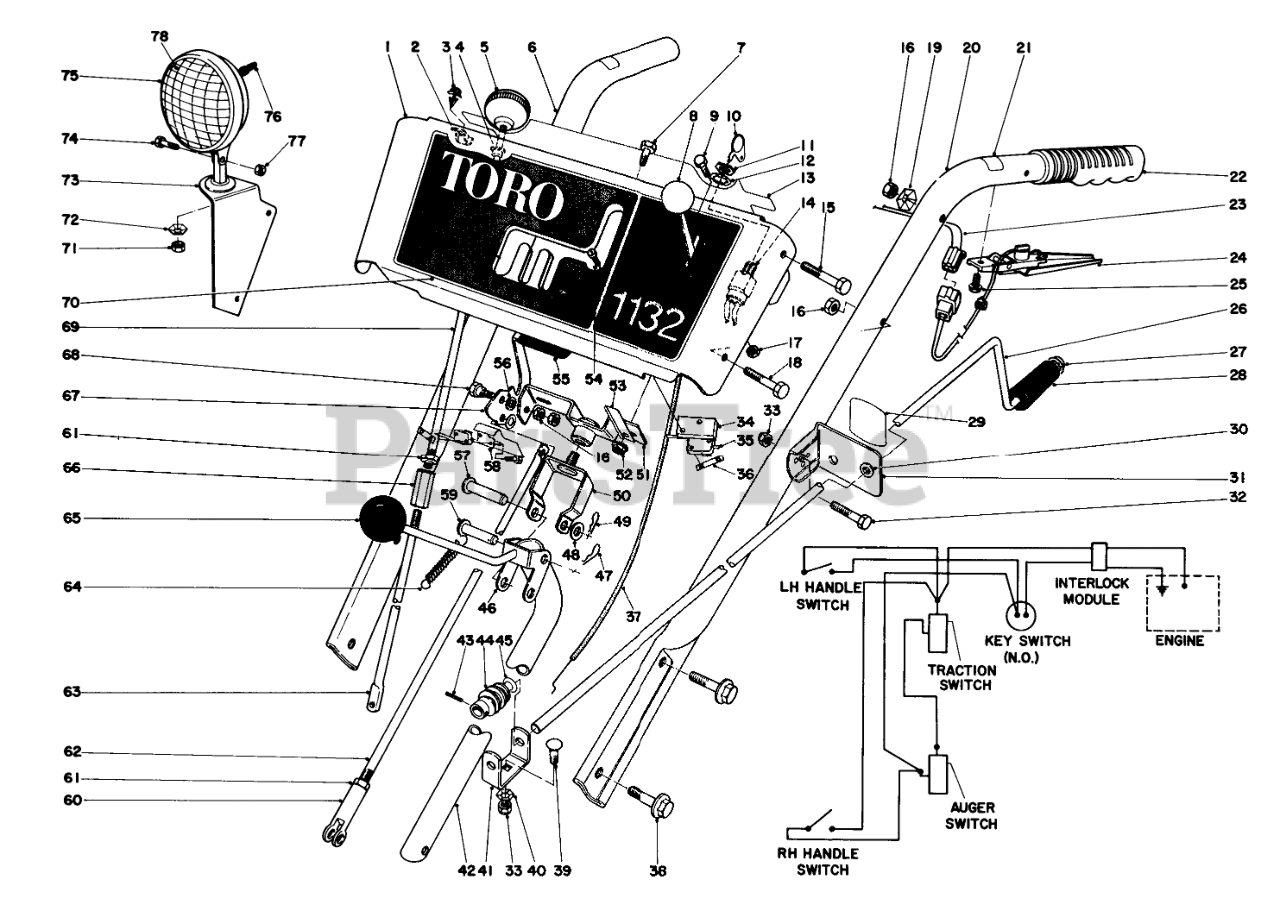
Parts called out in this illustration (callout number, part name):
1	Escutcheon Plate (Incl. Ref. #13&70)
2	WIRE CLAMP
3	Mounting Stud
4	NYLINER #6LI-FF TYPE 7
5	KNOB-LEVER
6	Handle Right
7	SCREW-HH
8	CONTROL KNOB
9	HEX HEAD SEMS 10-24X1/2
10	Key
11	NUT-HH
12	SCREW-SET
13	Decal-Escutcheon Back
14	Key Switch (Incl. Ref. #11 & 12)
15	SCREW-HH
16	NUT-LOCK, CONE
17	Nut
18	SCREW-HH
19	Washer
20	HANDLE LEFT
21	INTERLOCK DECAL
22	Grip Handle
23	WIRE HARNESS INTERLOC
24	INTERLOCK HDLE SWITCH
25	SCREW
26	Chute Control Rod
27	RETAINER-PUSH ON
28	GRIP-CONTROL, CHUTE
29	CHUTE DECAL
30	Bushing
31	Bracket-Chute Control Mtg. (Incl. Ref. #29 & 30)
32	SCREW-HH
33	NUT-LOCK, NI
34	SWITCH MTG PAD
35	SWITCH-MICRO
36	Speed Nut
37	Throttle Contrl
38	SCREW-HHF
39	BOLT-CARR
40	WASHER-LOCK
41	WORM BRACKET
42	Rod Traction Shift
43	PIN-SPRING
44	GEAR-WORM, CHUTE
45	WASHER-SPRING
46	SHIFT ROD WA
47	PIN-COTTER
48	WASHER-FLAT
49	PIN-HAIR
50	PIVOT BRKT WA
51	SWIVEL BLOCK WA
52	NUT-LOCK, HHF
53	Retainer Wire
54	SCREW-SPH
55	AUGER CLUTCH HND GRIP
56	WASHER-PLAIN
57	PIN-CLEVIS
58	SWITCH BRKT
59	PIN-CLEVIS
60	CLEVIS
61	NUT-HJ
62	DRAG LINK
63	LOWER WHL CLUTCH ROD
64	CONT ROD SPRING 0
66	WHL ROD COUPLING
67	Auger Clutch Handle
68	SCREW-SHOULDER
69	UP WHEEL CLUTCH ROD
70	Decal-Escutcheon
71	NUT-HEX
72	LOCKWASHER-PYRAMID
73	Lamp Mount
74	SCREW-HH
75	HEADLAMP ASM
76	BOOT-SWITCH
77	NUT-HEX, SIDE DEFORM
78	SEAL BEAM BULB 60W 12
